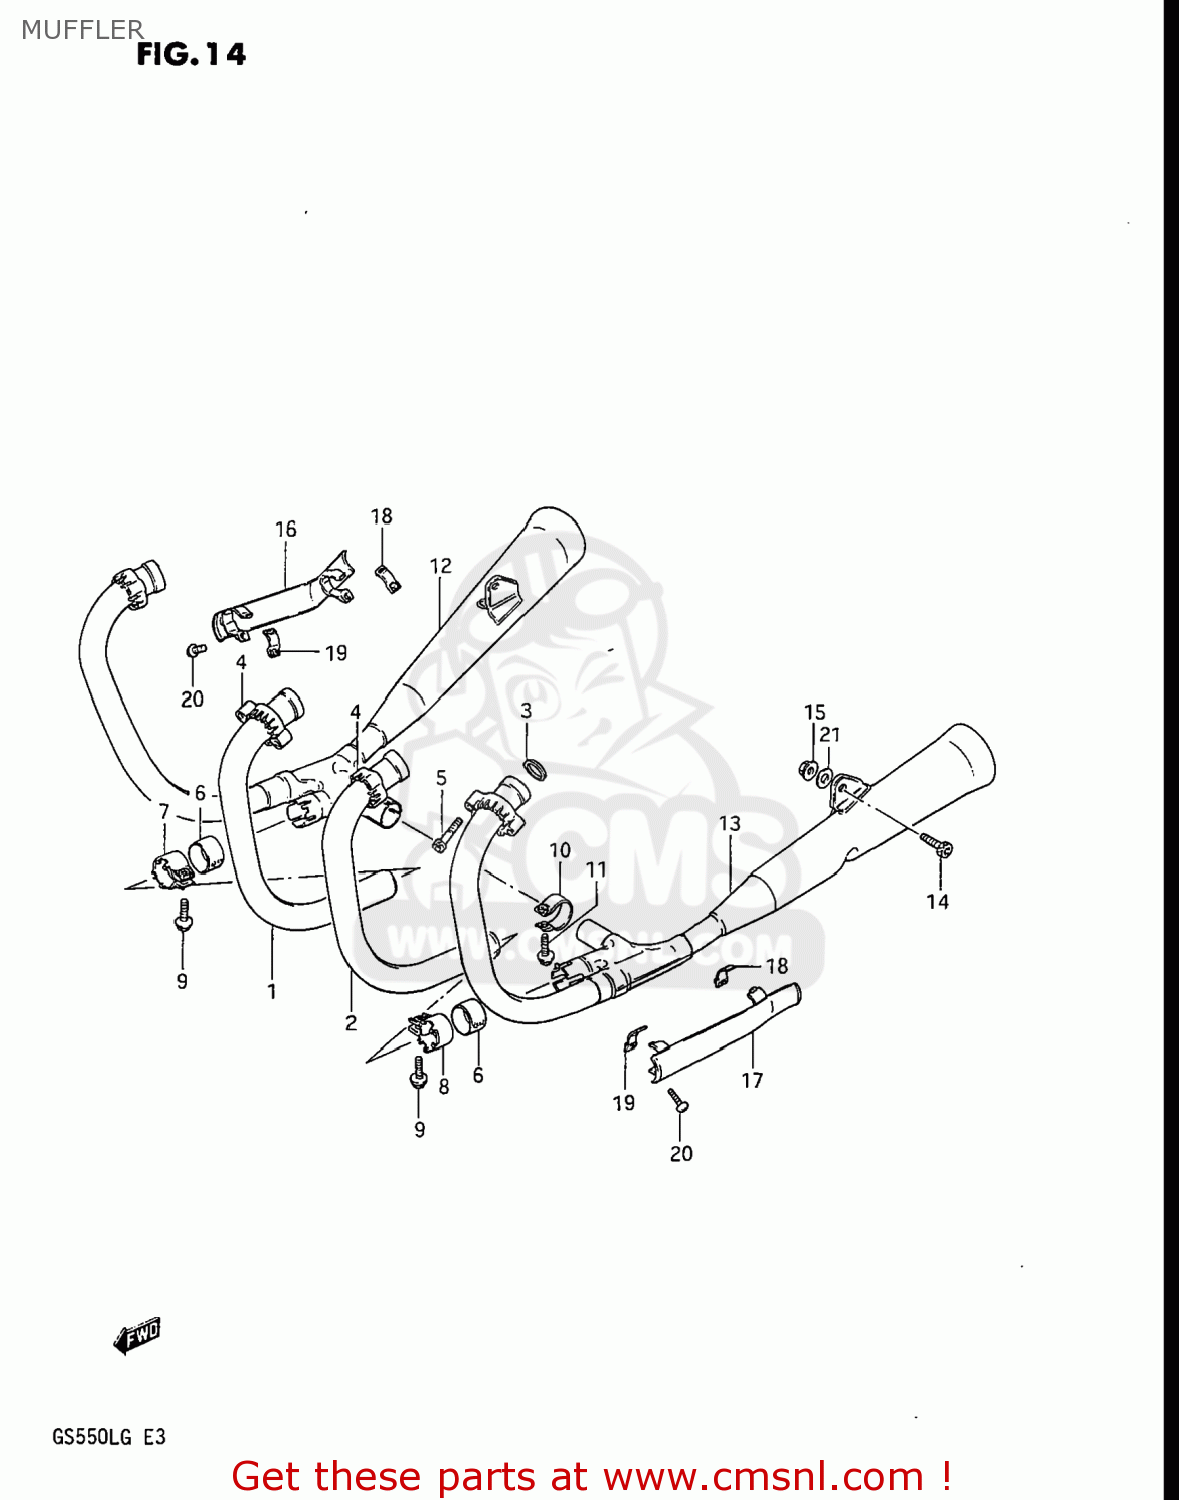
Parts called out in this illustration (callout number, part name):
1	PIPE.EXH.CENTER
2	PIPE,EXHAUST,CENTER,LEFT
3	GASKET,EXHAUST PIPE (NAS)
4	CLAMP,EXHAUST PIPE
5	BOLT
6	CONNECTOR,MUFFLER
7	CLAMP,MUFFLER CONNECTOR,R
8	CLAMP,MUFFLER CONNECTOR,L
9	BOLT
10	CLAMP,EXHAUST
11	BOLT,REAR
12	MUFFLER,RIGHT
13	MUFFLER ASSEMBLY
14	BOLT,REAR LH
15	NUT
16	COVER,MUFFLER,RIGHT
17	COVER,MUFFLER,LEFT
18	CLAMP,MUFFLER COVER
19	CLAMP,MUFFLER COVER
20	SCREW
21	WASHER
